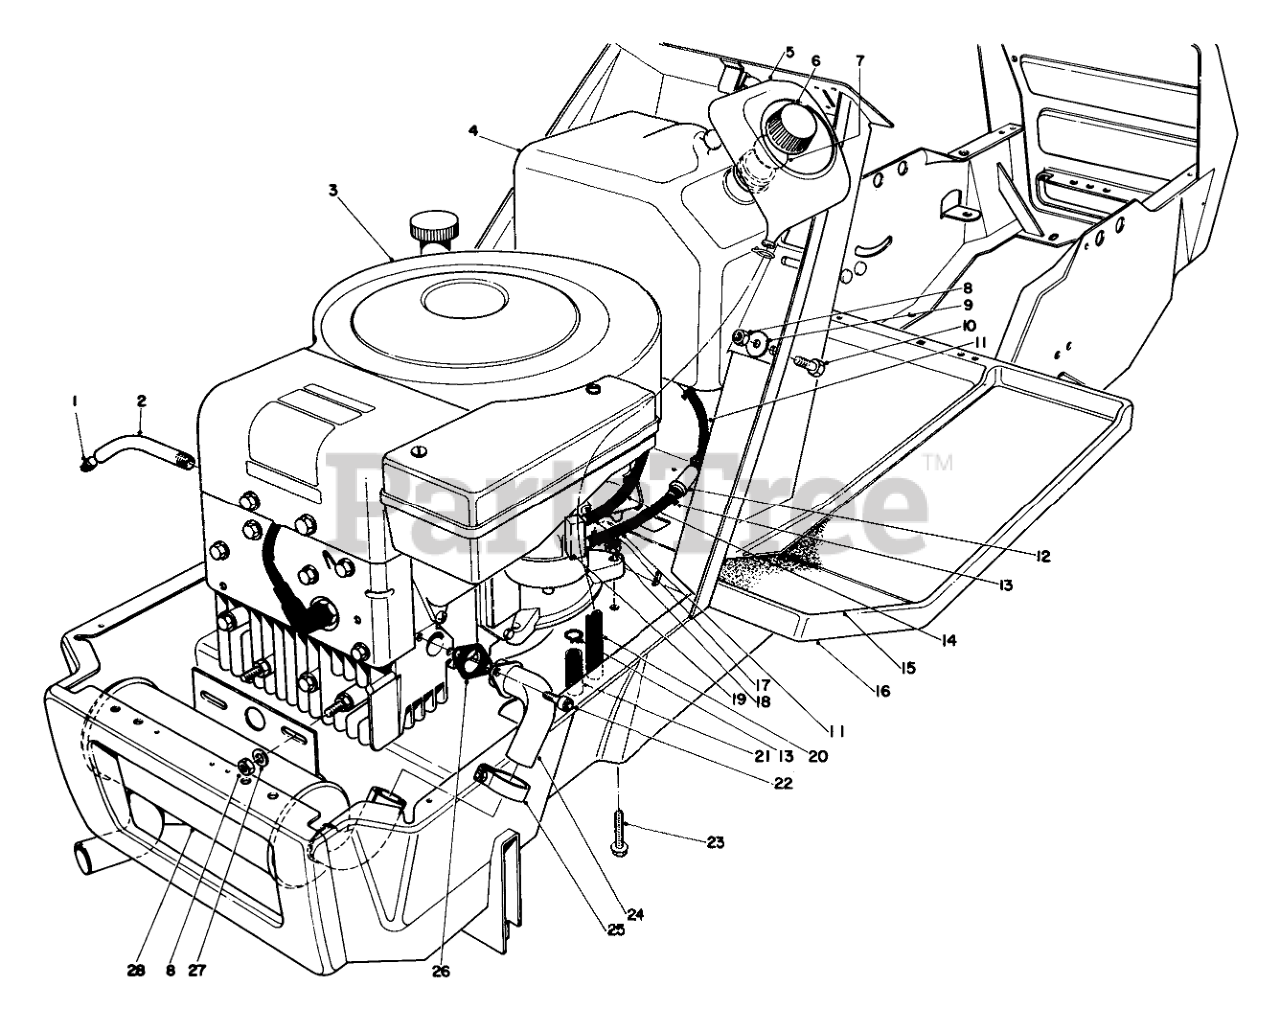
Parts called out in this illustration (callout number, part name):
1	PLUG-PIPE, SQH
2	OIL DRAIN TUBE
3	Engine
4	Gas Tank (Incl. Ref. #5)
5	Funnel Overflow
6	Gas Cap Assembly (Incl. Ref. #7)
7	Gasket Gas Cap
8	NUT-LOCK, CONE
9	WASHER
10	SCREW-HH
11	GAS HOSE
12	Fuel Filter
13	HOSE CLAMP
14	Gas Return Hose
15	LH FOOT TREAD
16	Frame
17	Clamp
18	NUT-LOCK, CONE
19	Fitting Carburetor
20	Hose Funnel
21	Hose Carburetor Drain
22	SCREW-HSH
23	SCREW-HH
24	10 HP EXHAUST PIPE WA
25	MUFFLER CLAMP
26	Gasket Exhaust
27	WASHER-PLAIN
28	EXHAUST MUFFLER 10 HP
